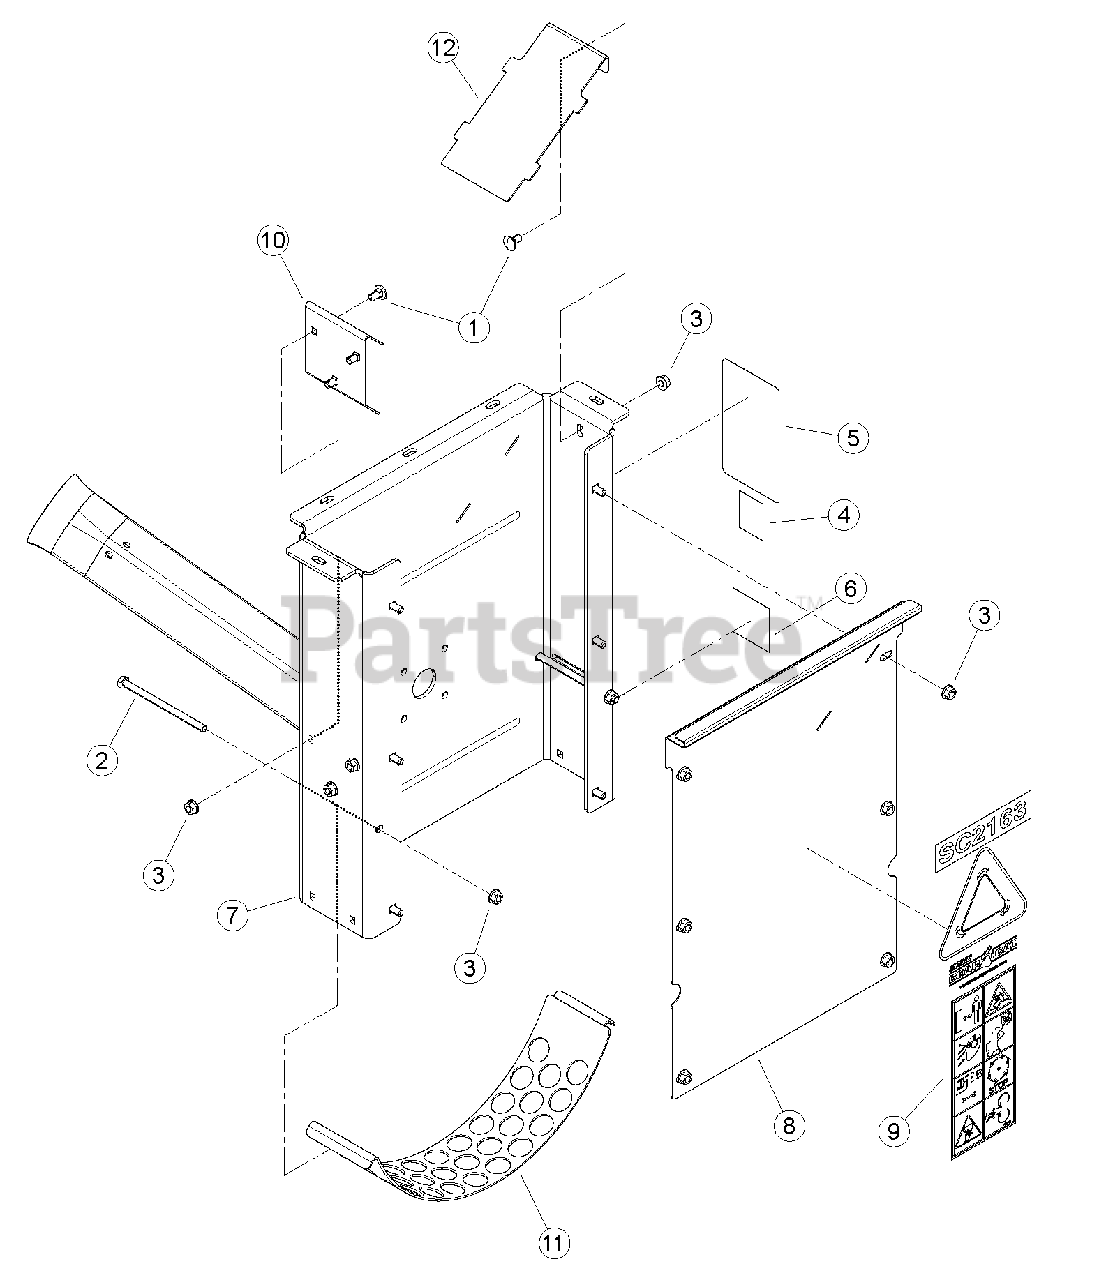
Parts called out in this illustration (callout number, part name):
1	BOLT, 5/16 X 5/8 CRG GR5 ZP
2	BOLT, 5/16 X 5" HHCS NC GR5 ZP
3	NUT, 5/16 SPIRAL LOCK
4	DECAL, ECHO BEARCAT QR CODE
5	DECAL, SC2163 CE INFORMATION
6	DECAL, SPARK ARRESTOR
7	WELDMENT, PLATE AND CHUTE
8	ASSEMBLY, SC2163 PANEL SERVICE
9	DECAL, SC2163 INFORMATION
10	PLATE, DEFLECTOR
11	SCREEN, SC2163 SMALL COARSE
12	PLATE, RESTRICTOR
